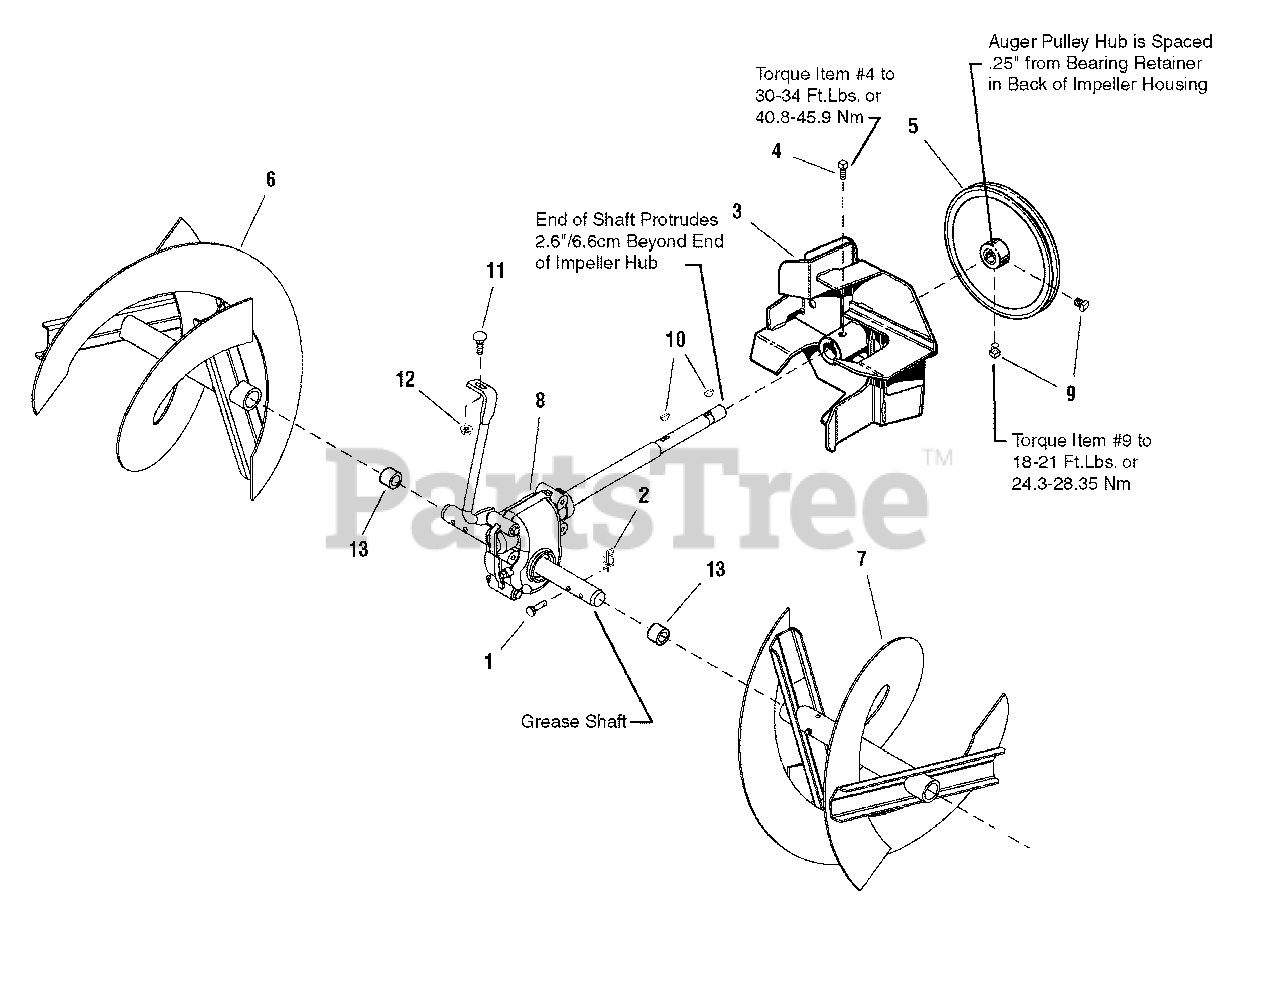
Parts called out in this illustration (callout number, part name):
1	PIN, SHEAR
2	COTTER PIN, 1/4" Self Locking
3	IMPELLER ASSEMBLY, Large Frame Snow
4	SCREW, Set, Square Head Cup Point 3/8-16 x 1/2 G8
5	PULLEY, w/Hub
6	AUGER ASSEMBLY, 24" & 26" R.H.
6	AUGER ASSEMBLY, 28" & 30" R.H.
6	AUGER ASSEMBLY, 32" R.H.
7	AUGER ASSEMBLY, 24" & 26" L.H.
7	AUGER ASSEMBLY, 24" & 30" L.H.
7	AUGER ASSEMBLY, 32" L.H.
8	GEAR BOX ASSEMBLY
9	SCREW, Set, Square Head Cup Point 5/16-18 x 1/2 G8
10	KEY, Woodruff
11	CARRIAGE BOLT, 5/16-18 x 3/4 G5
12	NUT, Hex Flange Whiz Lock, 5/16-18HEX FLANGE 5/16-18
